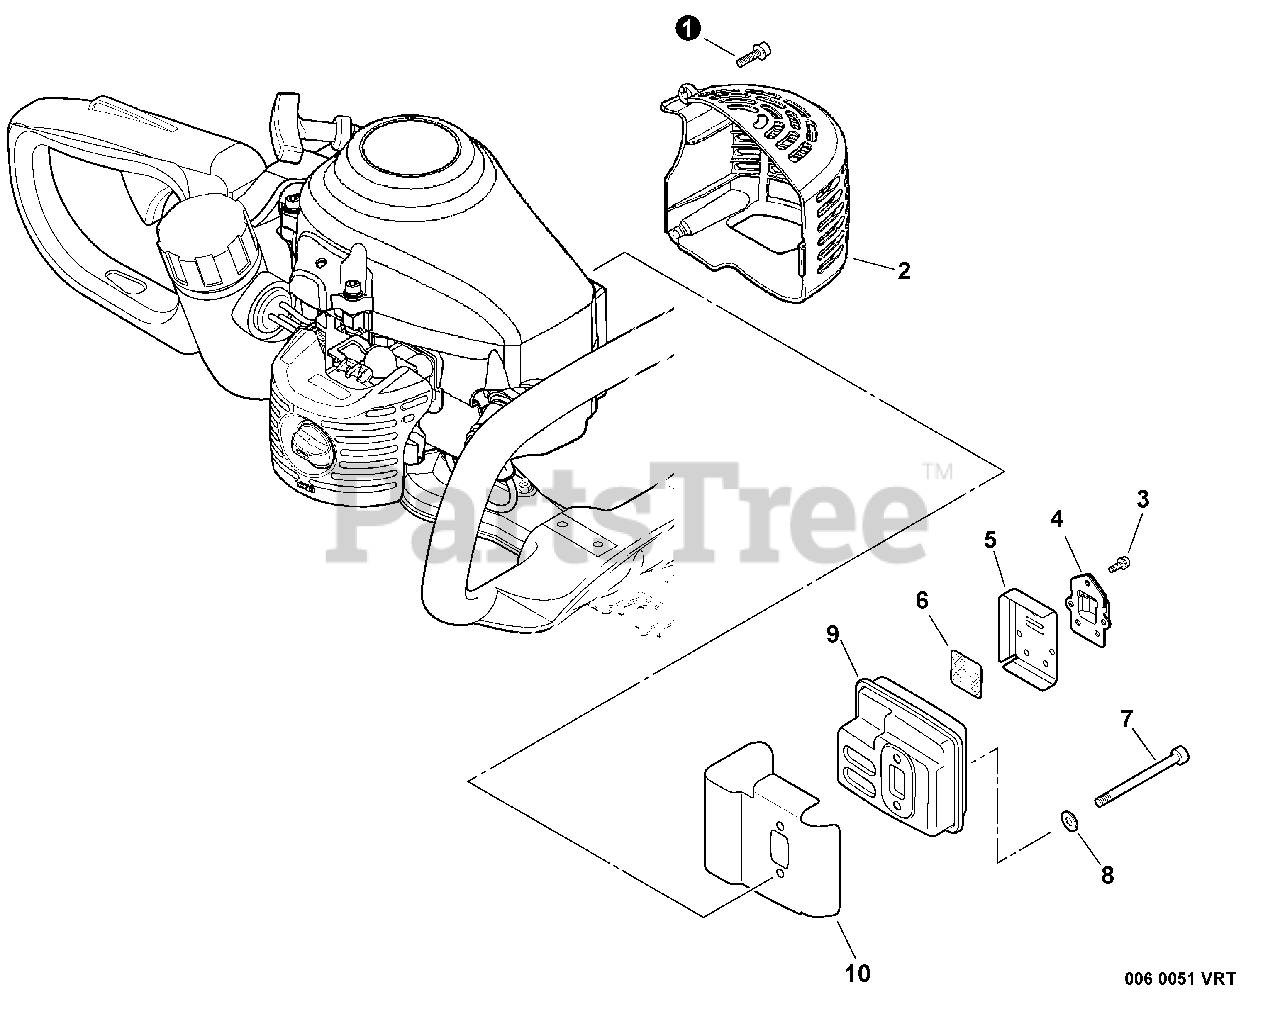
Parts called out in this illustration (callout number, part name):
1	SCREW - 5X16
2	COVER, EXHAUST
3	SCREW - 4X10
4	GUIDE, EXHAUST
5	GASKET, EXHAUST
6	SCREEN, SPARK ARRESTOR
7	SCREW - 5X55
8	WASHER - 5
10	SHIELD, EXHAUST
